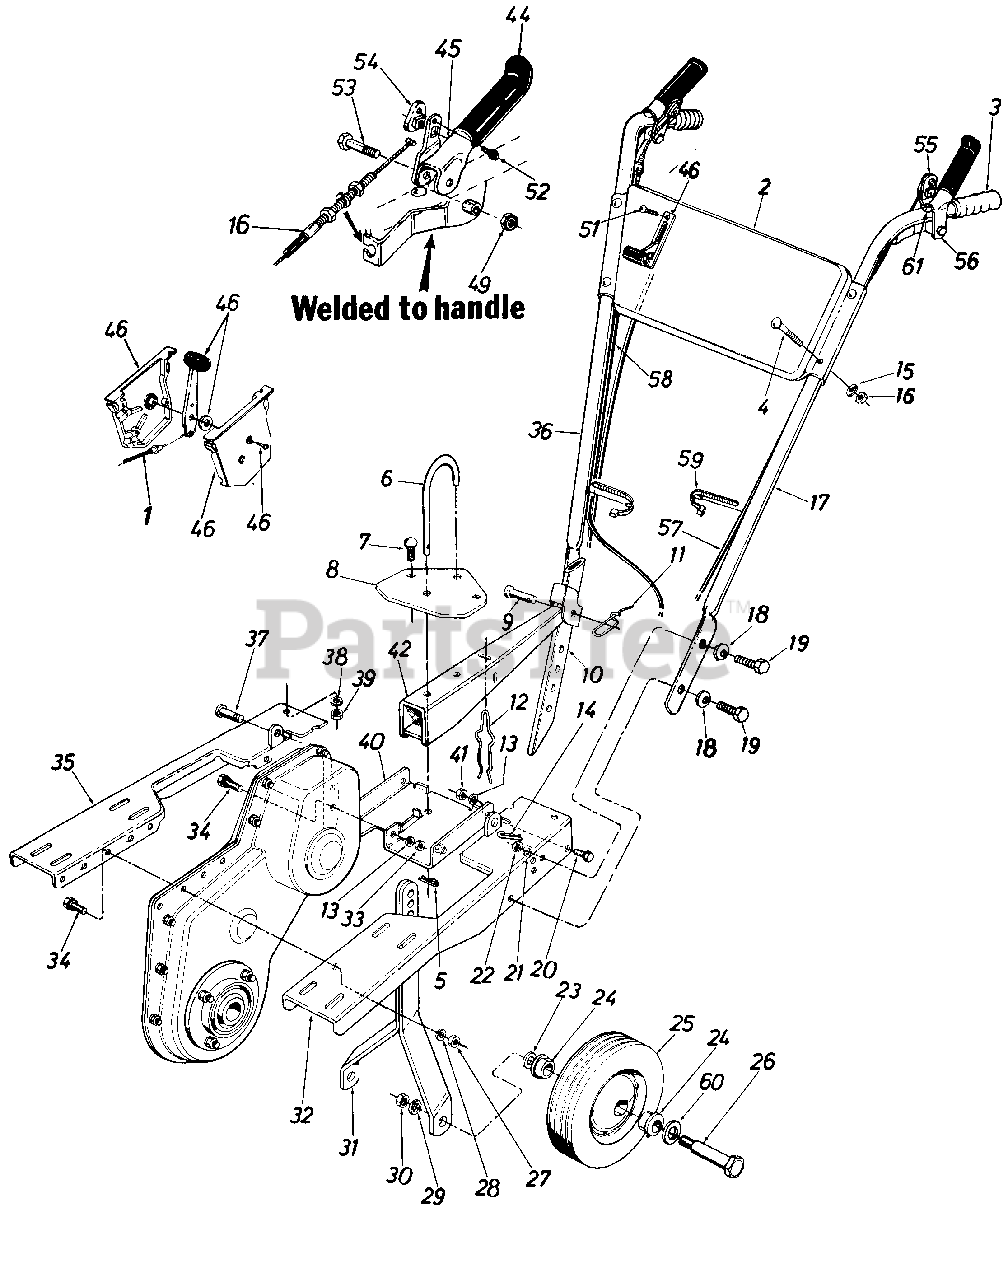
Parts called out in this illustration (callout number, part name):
1	Throttle Control Wire-35"
2	Handle Panel Ass'y.
3	Handle Grip
4	Carriage Bolt 5/16-18 x 1.75"
5	Internal Cotter Pin
6	"U"-Clevis Pin .500" Dia.
7	Carriage Bolt 5/16-18 x .75"
8	"U"-Channel Plate
9	Clevis Pin 1/2" Dia.
10	Depth Bar
11	Spring Pin
12	Depth Bar Spring
13	L-Wash. 5/16" I.D.*
14	Internal Cotter Pin
15	L-Wash. 5/16" I.D.t
16	Hex Nut 5/16-18 Thd.t
19	Hex Bolt 3/8-16 x 1.00" Lg t
20	Hex Bolt 5/16-18 x .75" Lg t
21	L-Wash. 3/8" I.D.t
22	Hex Nut 3/8-16 Thd.t
23	Belleville Wash. .505 I.D. x 1.00" O.D.
24	Fl. Bearing w/Flats .631 I.D.
25	Wheel Ass'y. Comp. 10 x 1.75
26	Shoulder Bolt .625" Dia. x 2.75" Lg.
27	Hex Nut 5/16-18 Thd.t
28	L-Wash. 5/16" I.D.t
29	L-Wash. 1/2" I.D.t
30	Hex Ins. L-Nut 1/2-20 Thd.
31	Wheel Bracket Ass'y.
32	Engine"U"-Channel Ass'y.-L.H.
33	Hex Nut 5/16-18 Thd.
34	Hex Sems Bolt 5/16-18 x 1.00" Lg.
35	Engine"U"-Channel Ass'y.-R . H .
36	Handle-R.H.
37	Clevis Pin .375" Dia.
38	L-Wash. 5/16" I.D.
39	Hex Nut 5/16-18 Thd.
40	"U"-Channel Bracket Ass'y.
41	Hex Nut 5/16-18 Thd.
42	Tailpiece Ass'y.
44	Clutch Vinyl Grip
45	Clutch Grip Ass'y.-R.H.
46	Throttle Control Box Ass'y.
49	Hex Ins. L-Nut 3/8-24 Thd.
51	Self-Tap Scr. #10 x 1/2" Lg.
52	Self-Tap Scr. #10 x .44" Lg.
53	Hex Bolt 3/8-24 x 2.0" Lg.
54	Barrel Cable Hold-Down-R.H.
55	Barrel Cable Hold-Down-L.H.
57	Control Cable
58	Control Cable
59	Cable Tie
60	Fl-Wash. .640 I.D. x 1.24"
61	Bumper
